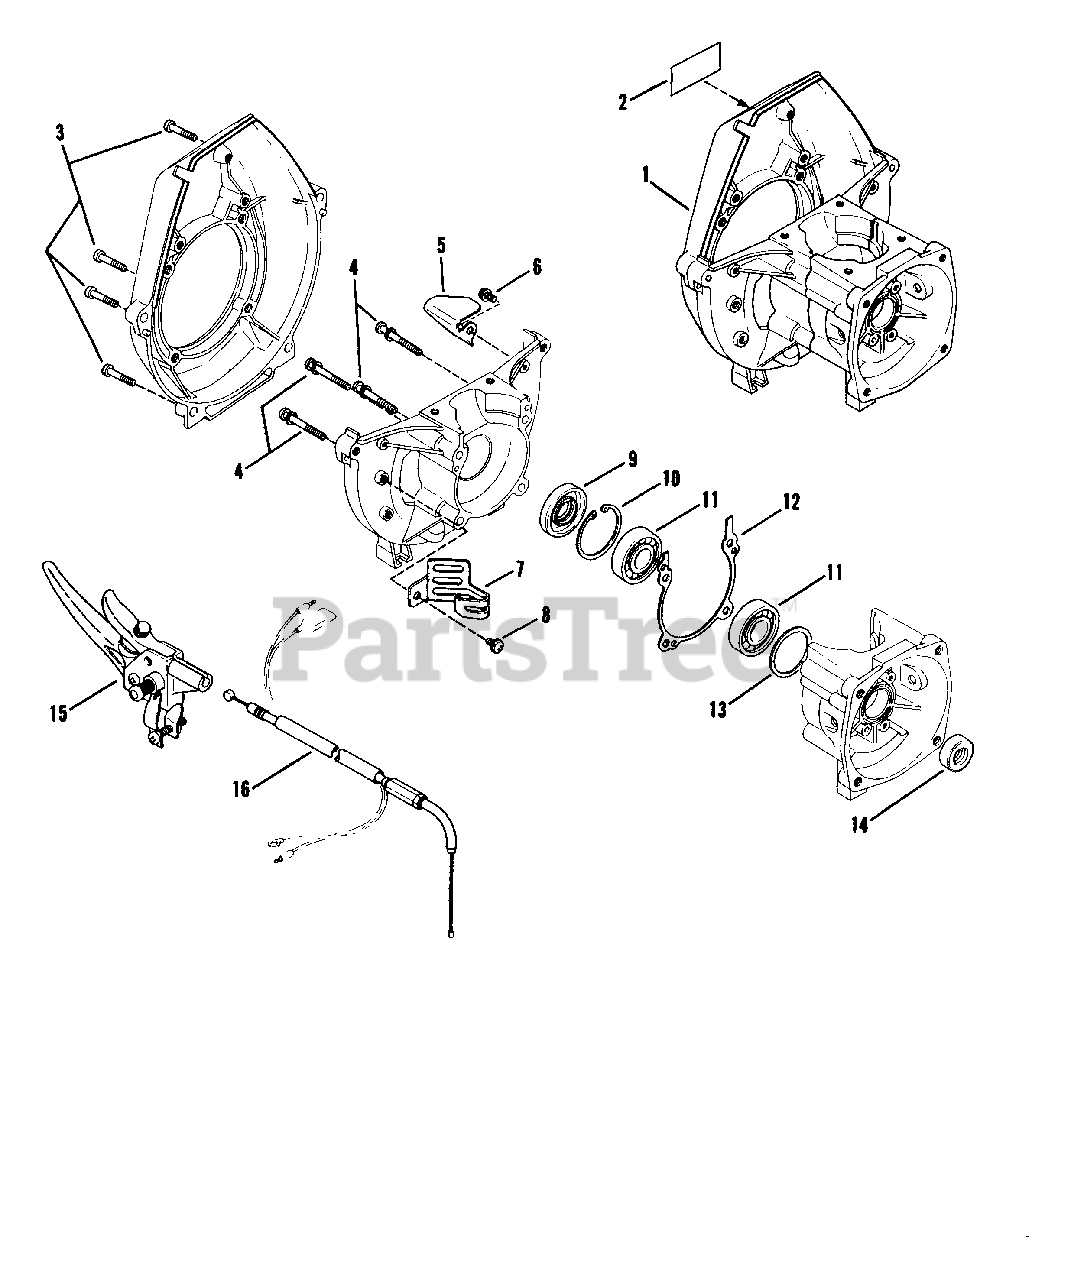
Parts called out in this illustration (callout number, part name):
1	CRANK CASE ASSM'Y.
2	DECAL, Serial Number
9	SEAL, Oil
10	SNAP RING
11	BEARING
12	GASKET, Crankcase
13	SHIM (Set of 3)
14	SEAL, Oil
15	LEVER, Throttle
16	WIRE, Throttle
